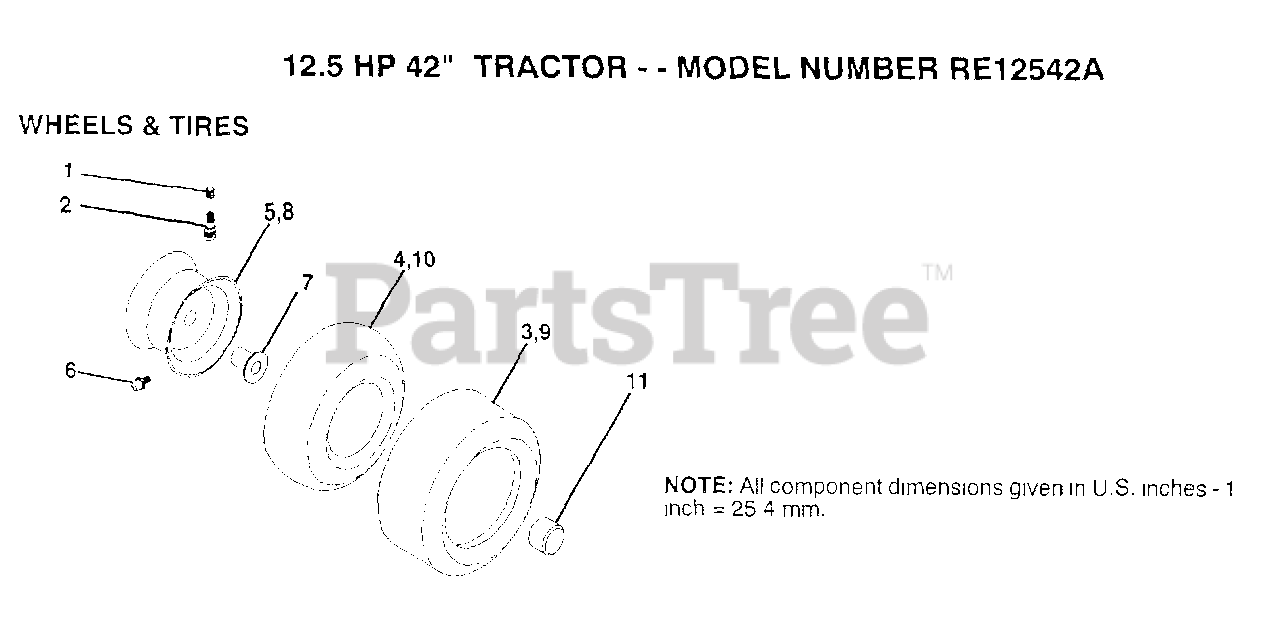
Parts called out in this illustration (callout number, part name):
1	VALVE CAP
2	VALVE STEM LT
4	TUBE.5.3/4.5/6
6	FITTING LT
7	"FLANGE, BEARING"
10	TUBE.18X9.5-8
11	HUB CAP
